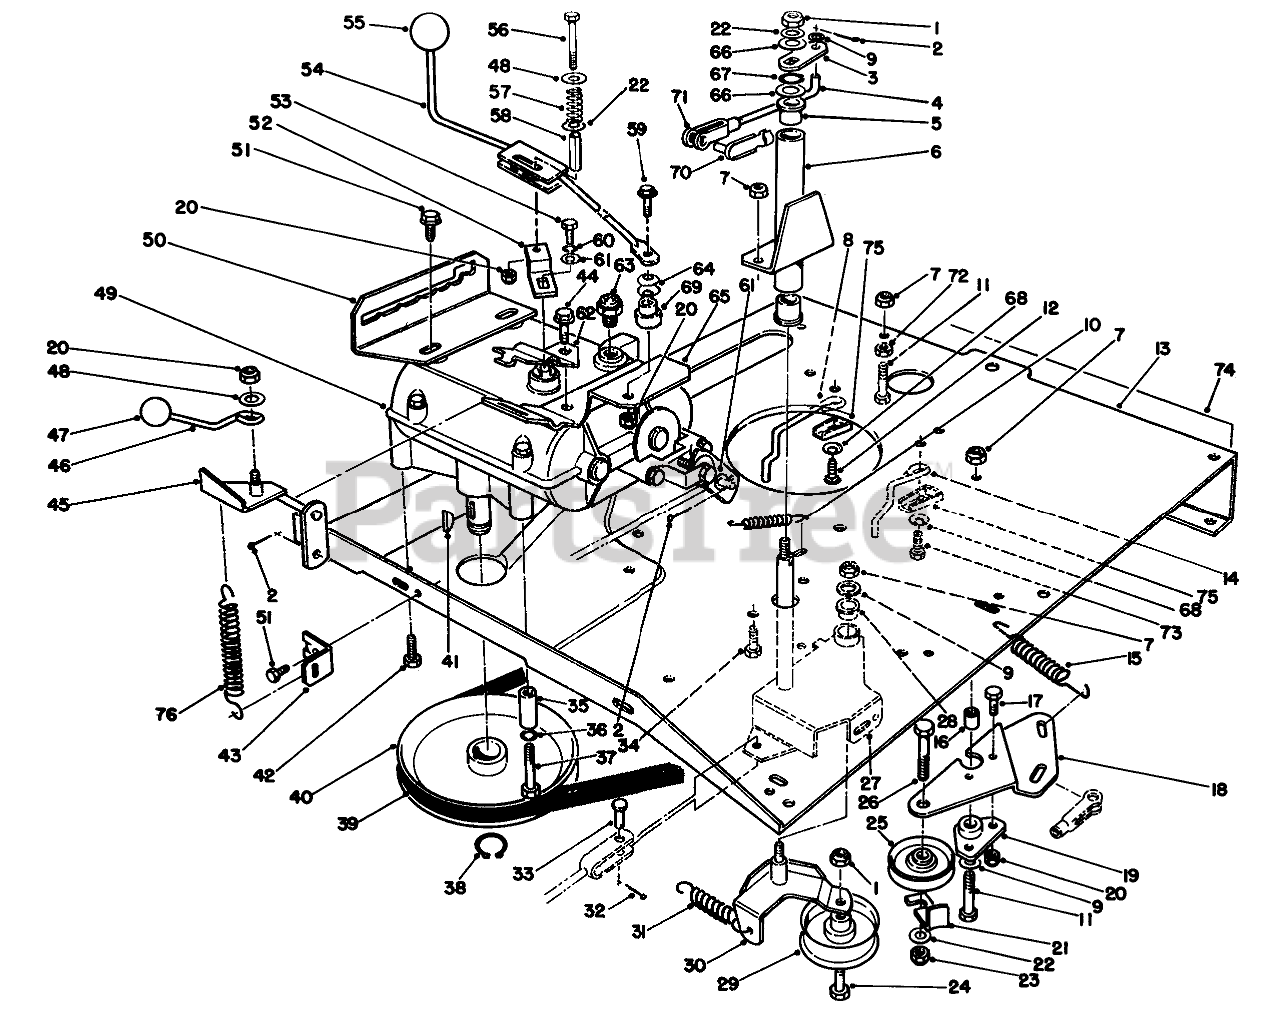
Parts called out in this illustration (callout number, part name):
1	NUT-LOCK, NI
2	PIN-COTTER
3	Flat-Deck Engage
4	LINK-DECK ENGAGE
5	BUSHING-FLANGE
6	Tube W.A.-Pivot (Incl. Ref. #5)
7	NUT-LOCK, NI
8	ENG BELT GUIDE R.
9	WASHER-PLAIN
10	SPRING-RETURN, BRAKE
11	SCREW-HH
12	BOLT-CARR
13	Plate-Engine
14	GUIDE-ENG. BELT L.
15	SPRING-TRACTION
16	SPACER-PIVOT
17	SCREW-HH
18	Plate-Idler Mount
19	MOUNT-TRACTION PIVOT
20	NUT-LOCK, NI
21	RETAINER-BELT
22	WASHER-FLAT
23	NUT-LOCK, NI
24	SCREW-HH
25	PULLEY-IDLER
26	SCREW-HH
27	Bracket-Arm, Idler (Incl. Ref. #28)
28	BUSHING-FLANGE
29	PULLEY-IDLER
30	Idler-Plate, Mount
31	SPRING-IDLER
32	SCREW-HSH
33	PIN-CLEVIS
34	SCREW-HH
35	GUIDE-BELT
36	WASHER-LOCK
37	SCREW-HH
38	RING-SNAP, EXTERNAL
39	67BELT, TRACTION DRIVE
40	PULLEY
41	KEY-WOODRUFF
42	5/16-18 X 5/8 SEMS SC
43	BRKT-SPRING MT
44	SCREW-HWHTF
45	Lever W.A.-Deck Engage
46	ROD-ENGAGE
47	KNOB-CONTROL
48	WASHER-FLAT
49	TRANSMISSION
50	Gate-Shift
51	SCREW-HWHTF
52	LEVER-SHIFT
53	SCREW-HH
54	Lever W.A.-Shift
56	SCREW-HH
57	SPRING-COMPRESSION
58	SPACER-SPLIT
59	SCREW-HH
60	WASHER-LOCK
61	WASHER-FLAT
62	BRKT-DECK ENG UPPER
63	NEUTRAL SWITCH
64	WASHER-BELLEVILLE
65	BRKT-DECK ENG. SHIFTER
66	WASHER
67	RING-RETAINING
68	WASHER-BELLEVILLE
69	SPACER-PIVOT
70	CLEVIS PIN ASM
71	CLEVIS-ADJ
72	NUT-JAM
73	SCREW-FLOW, TAPTITE
74	DECAL - REAR FRAME TORO
75	ANCHOR-GUIDE, BELT
76	SPRING-IDLER
